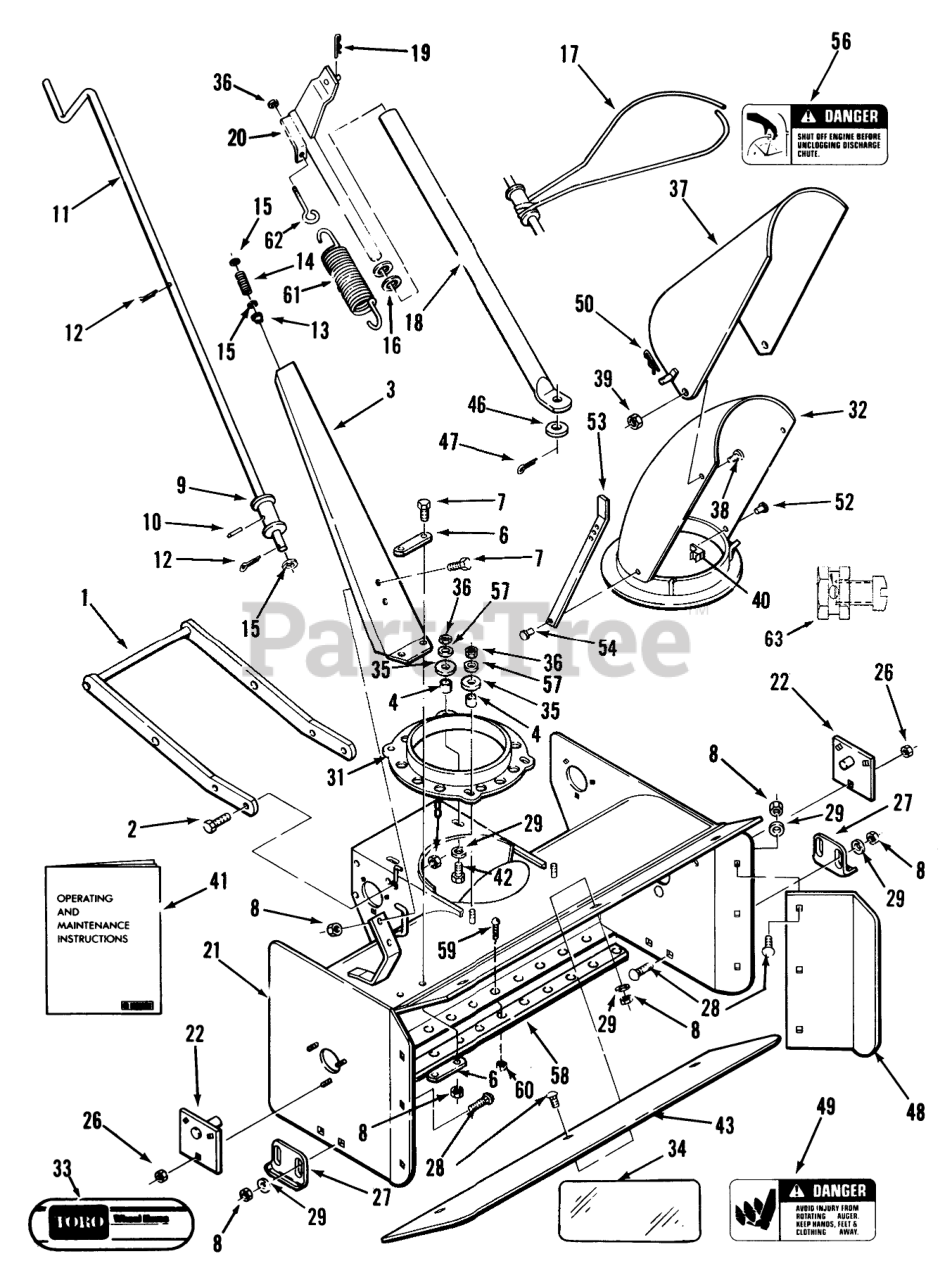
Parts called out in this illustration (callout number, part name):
1	Frame-Mounting
2	Bolt
3	Crank Support
4	SPACER
6	Bar-Reinforcing
7	Bolt
8	Nut
9	ASSY TUBE CRANK R
10	ROLL PIN 1/4 X 1-1/4
11	CRANK R
12	Pop Rivet
13	NYLINER BUSHING
14	SPRING-COMPRESSION
15	Washer
16	Washer
17	CABLE
18	ASSY LIFT TUBE R
19	Hairpin Cotter
20	LIFT ROD ASM
21	Wrapper
22	Plate
26	Nut
27	Skid
28	Bolt
29	Washer
31	COLLAR
32	S/A SHROUD R
33	Decal
34	DECAL-OVERLAY
35	WASHER
36	NUT
37	Deflector
38	MACH. SCREW
39	Nut
40	CLAMP
42	Bolt
43	Plate
46	WASHER
47	Cotter Pin
48	Plate
49	DECAL DANGER
50	Hairpin
52	RIVET-4
53	ARM R
54	RIVET
56	DECAL DANGER
57	WASHER
58	Reversible Scraper
59	Bolt-Carriage
61	SPRING
62	EYEBOLT
